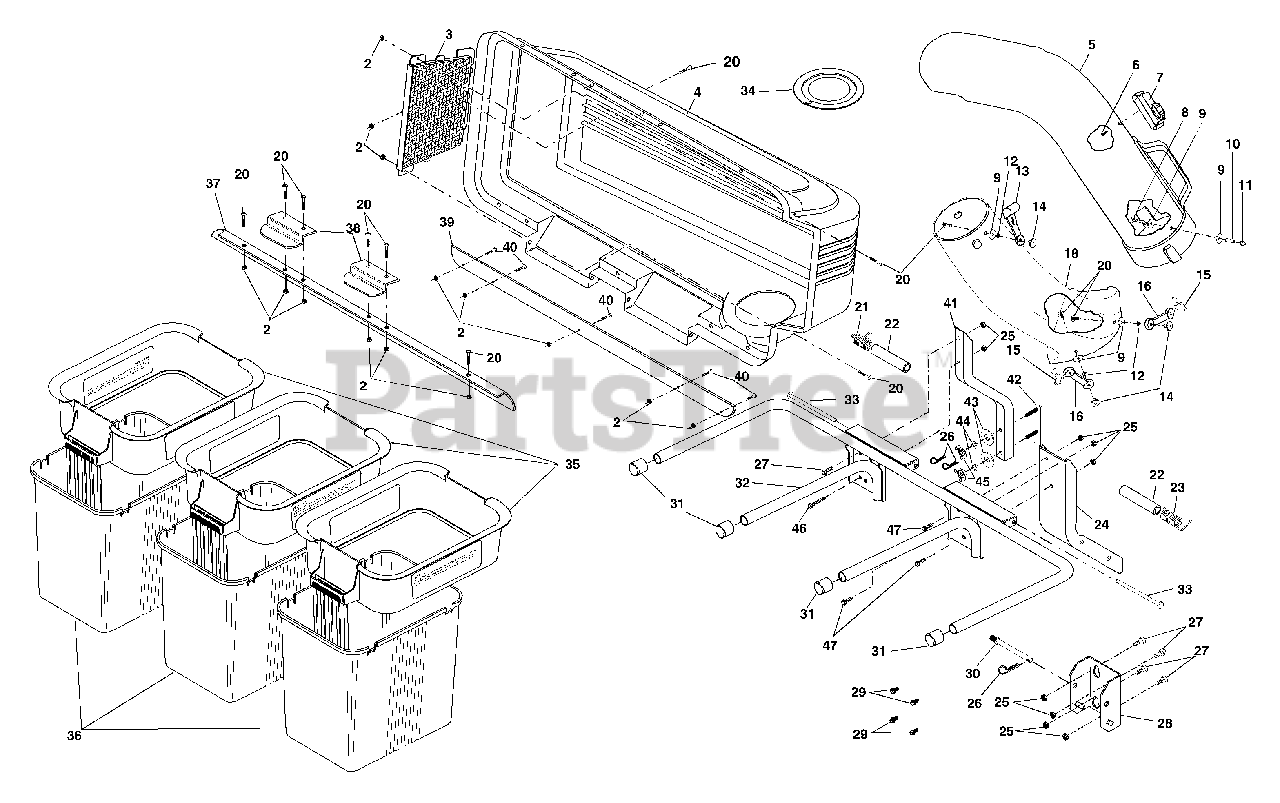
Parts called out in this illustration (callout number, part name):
2	Nut, Crownlock #10-24
3	Screen, Cover
4	Cover
5	Chute, Upper
6	Screw, Special #10-14x1/2
7	Dump Bag Indicator
8	Screw, #10-24 x 1-1/8
9	Washer 3/16x3/4x16 Ga.
10	Spacer, Split
11	Nut, Acorn #10-24
12	Washer, lock
13	Latch, Chute
14	Nut, Weld
15	Latch, Hook
16	Rubber, Latch
18	Chute, Lower
20	Screw #10-24 x 5/8
21	Spring, Cover L.H. (black)
22	Spacer, Cover
23	Spring, Cover R.H. (gray)
24	Post, Support
25	Locknut 5/16 x 18
26	Spring, Retainer
27	Bolt, Hex 5/16-18 x 3/4
28	Bracket, Mounting
29	Shoulder Bolt,Self Tapping
30	Pin, Support Post
31	Plug, Tubing End
32	Bagger, Frame
33	Pin, Hinge
34	Gasket, Cover
35	Container, Top
36	Container, Bottom
37	Seal, Cover
38	Latch Handle, Cover
39	Strip, Reinforcement
40	Screw #10-24 x 1/2
41	Bagger, Support Tube
42	Reinforcement Plate
43	Washer 11/32x1.5x10 Ga.
44	Washer, lock
46	Bolt, Hex 5/16-18 x 2-1/4
47	Carriage Bolt 5/16-18 x 3/4
